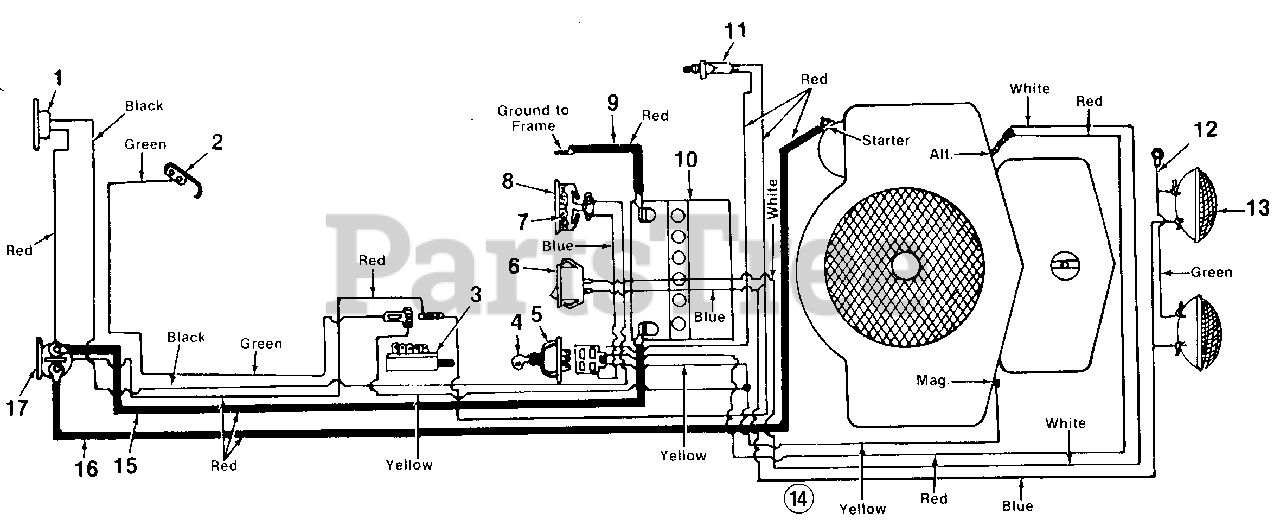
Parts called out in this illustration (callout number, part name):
1	Circuit Breaker
2	Spring Switch
3	Safety Switch Dpst.
4	Ignition Key
5	Ignition Switch
6	Headlight Switch
7	Foam Strip
8	Ammeter
9	Grounding Wire 14.0" Lg.
10	12 Volt Battery
11	Safety Switch
12	Ground Wire
13	Headlight
14	Wire Harness
15	Electric Wire 27.0" Lg.
16	Electric Wire 32.5" Lg.
17	Solenoid
